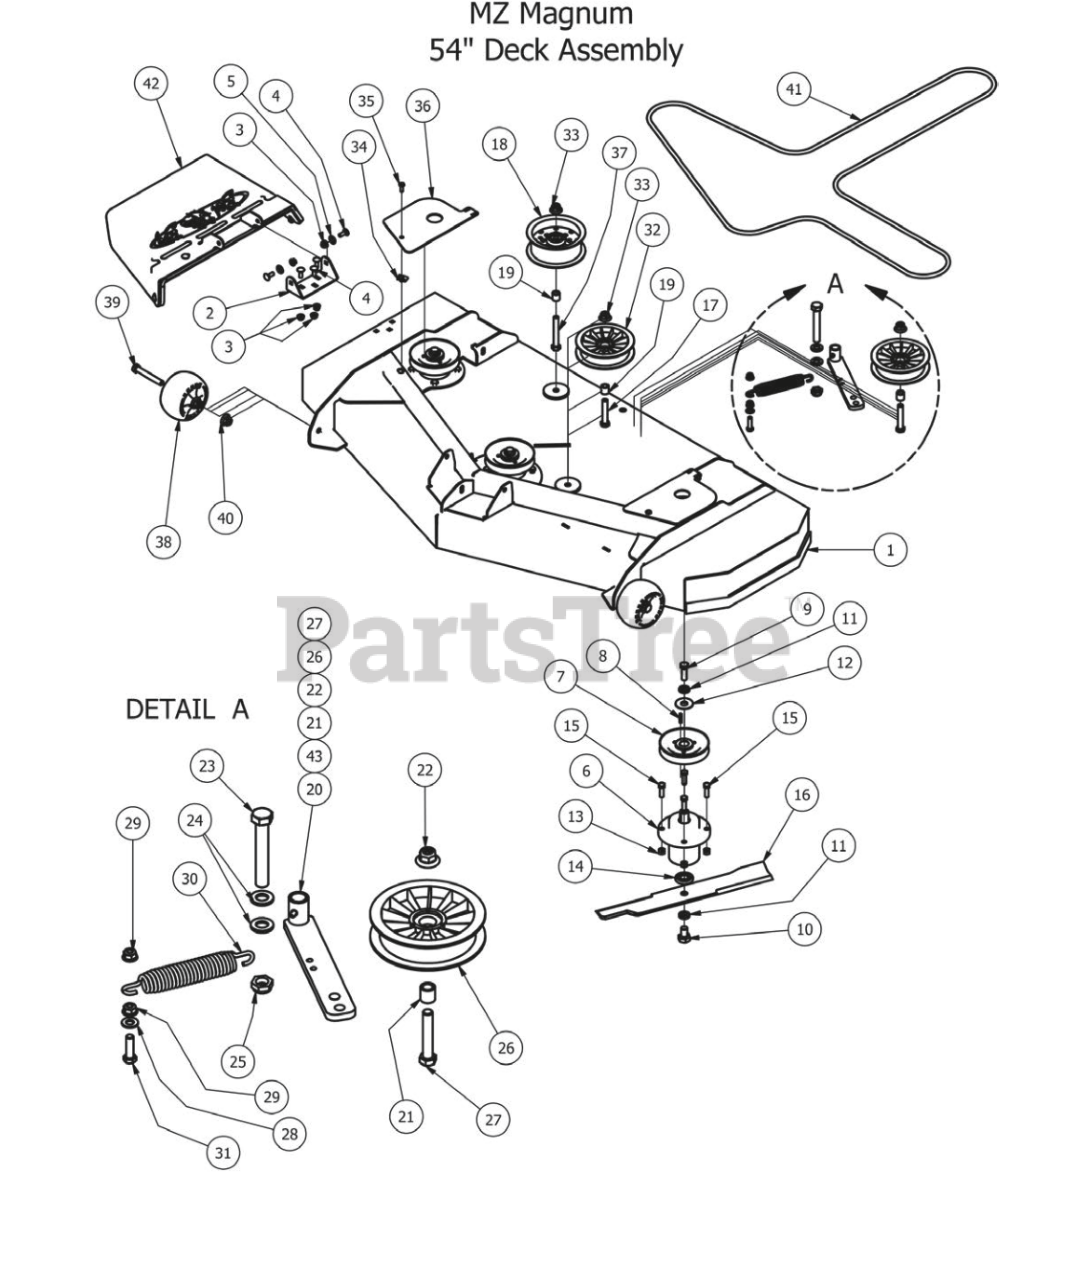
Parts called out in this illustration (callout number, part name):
1	54 MZ Deck
2	Chute Hanger 48 MZ
3	5/16" Nylon Flange Nut
4	5/16" x 7/8" Carriage Bolt
5	.360 ID Plastic Washer
7	MZ Deck Pulley
8	3/16 x 1 Square Key
9	1/2"-20 x 1 1/2 - Grade 5 Fine Thread Bolt
10	5/8" x 1 1/2" Grade 8 Bolt
11	5/8" Lock Washer
12	Type B Plain Washer
13	3/8" Hex Nut
14	Spindle Bearing
15	3/8" x 1 1/4" Hex Bolt
16	54" MZ Fusion Blade
17	1/2" x 2 3/4" Hex Bolt
18	5 3/4 flat idler-32fI-92-008
19	3/4 OD x 1/2 ID x 3\4 Length
20	Deck Idler 2009 AOS
21	3/4 OD x 1/2 ID x 3\4 Length
22	1/2-13 Nylon Flange Nut-Orange
23	5/8" x 4" Hex Bolt
24	.635 ID Plastic Washer
25	5/8" Nylock (1/2 Jam)
26	Plastic Idler Pulley
27	1/2" x 2 3/4" Hex Bolt
28	3/8" Flat Washer
29	3/8" Nylock Flange Nut
30	2009 Deck/Pump Idler Spring
31	3/8" x 1 1/4" Hex Bolt
32	Plastic Idler Pulley
33	1/2-13 Nylon Flange Nut-Orange
34	1/4-20 Cage Nut
35	1/4" x 3/4" Hex Bolt
36	MZ Pulley Cover 48"
37	1/2-13 x 3 1/2 GR 5 Hex Bolt
38	Deck Wheel
39	1/2 x 3 1/2 Flange Bolt Grade 8
40	1/2-13 Nylon Flange Nut-Orange
41	B 138 Belt 54" MZ Magnum
42	MZ Discharge Assembly
43	MZ Deck Idler Assembly (Components 20,21,22,26,27)
